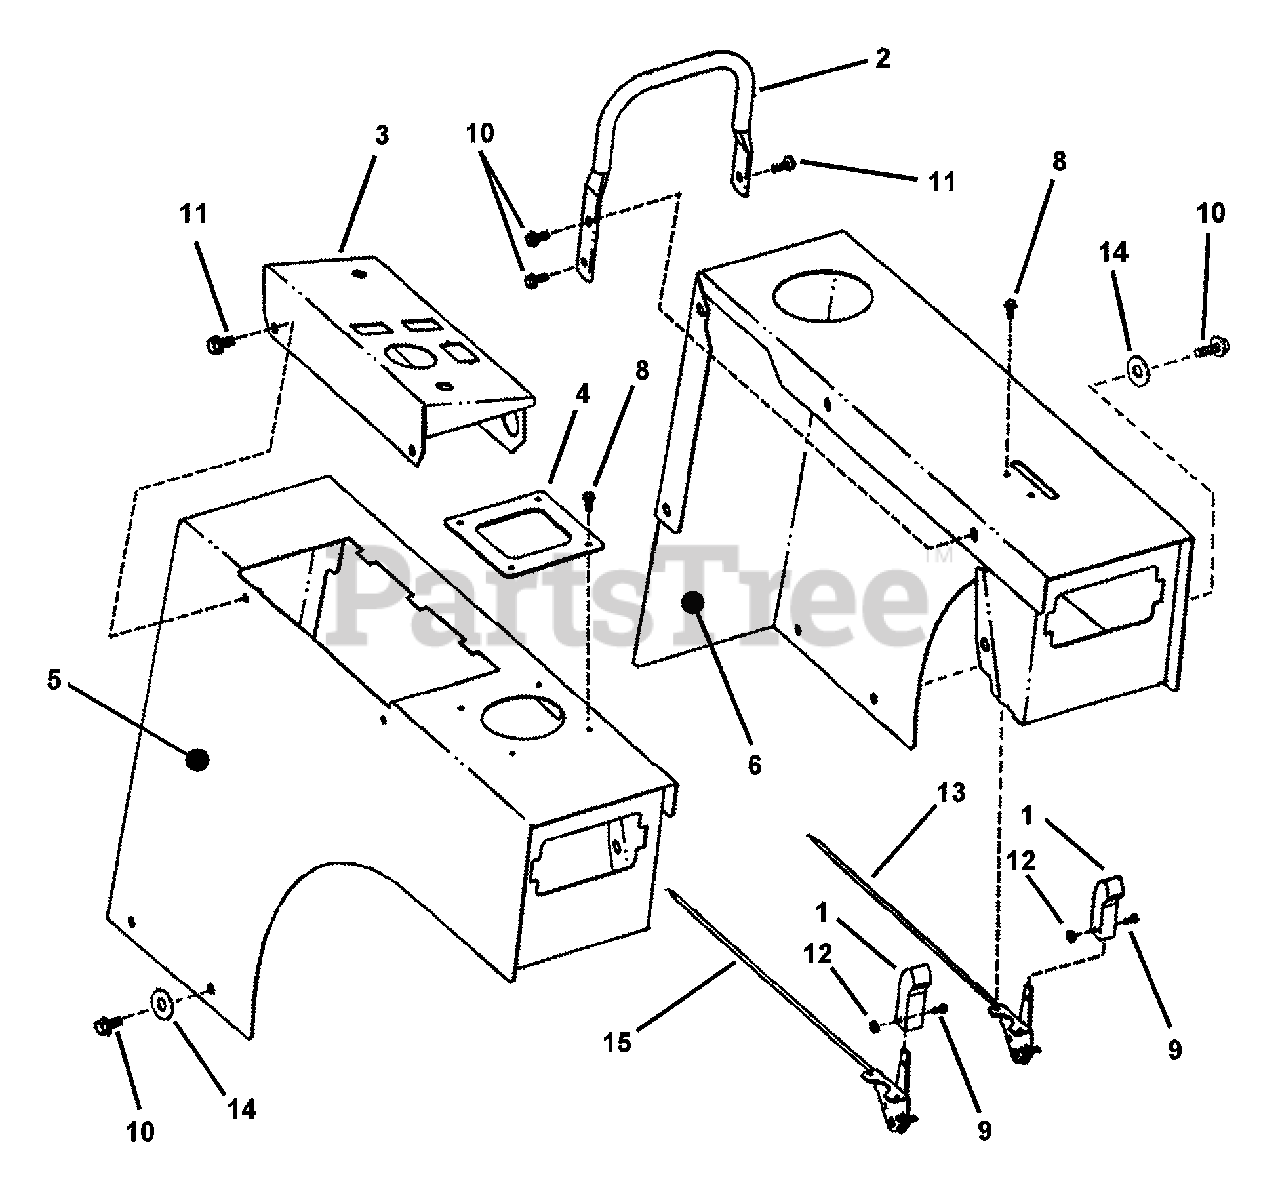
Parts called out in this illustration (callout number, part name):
1	LEVER, Throttle Control
2	HANDLE, 5/8" Tubing
3	PANEL, Instrument
4	PLATE, Joystick Control
5	FENDER, Right Hand
6	FENDER, Left Hand
8	SCREW, #10-24 x 1/2" Hex Washer Self-Tap (Torx)
9	SCREW, #8-32 x 3/8" Machine
10	SCREW, 5/16-18 x 5/8" Hex Self-Tapping
11	SCREW, 1/4-20 x 3/4" Hex Flange Lock
12	NUT, #8-32 Hex
13	CONTROL, Engine Speed 62.0"
13	CONTROL, Engine Speed 31.0"
14	WASHER, 5/16" I.D. Flat
15	CONTROL, Choke 62.87"
